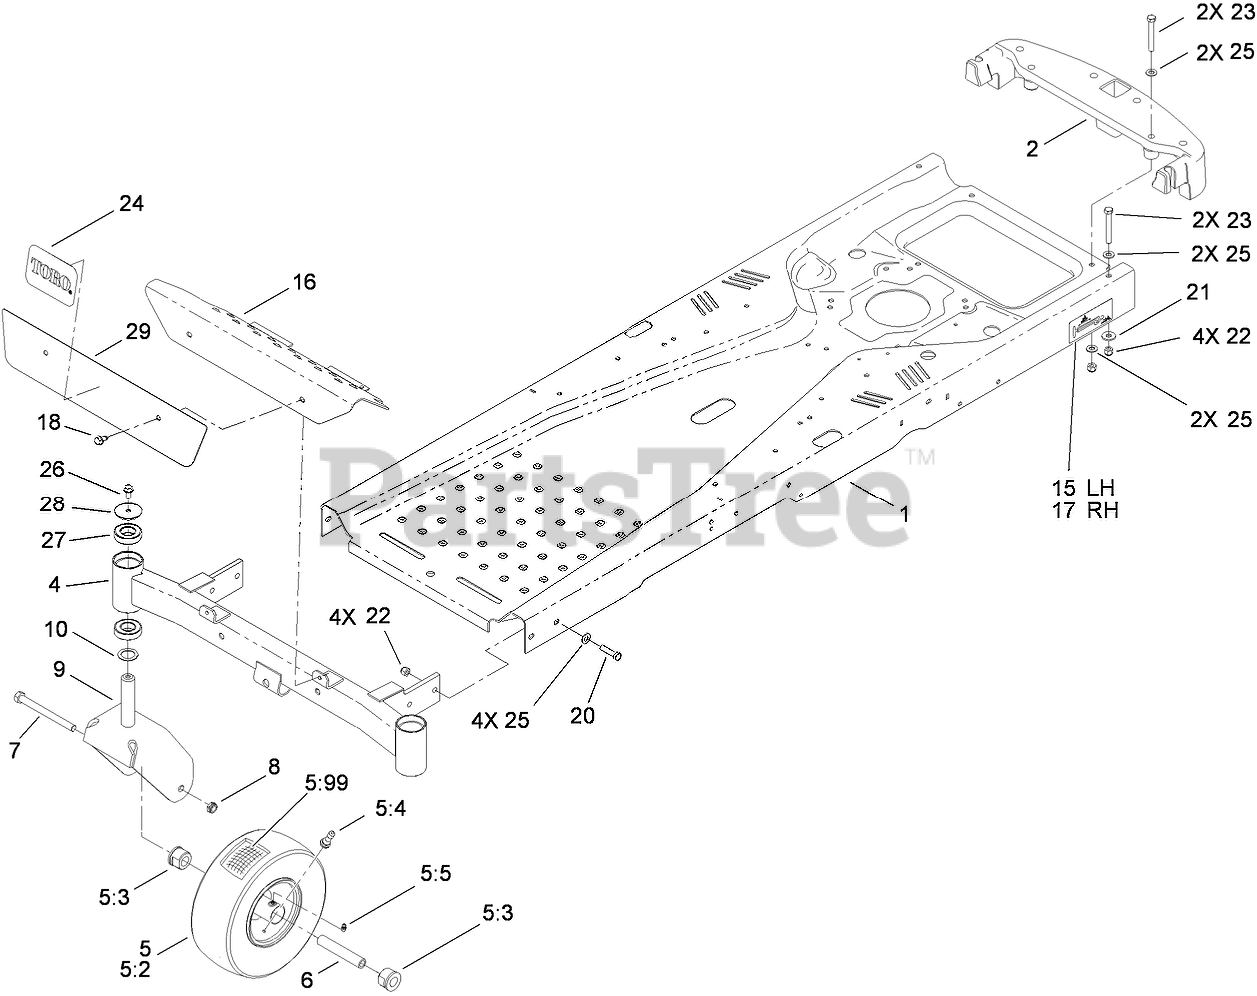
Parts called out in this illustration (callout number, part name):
2	BUMPER-REAR
4	FRONT AXLE ASM
5	11 INCH TIRE AND WHEEL ASM
5:2	TIRE-RIBBED
5:3	BUSHING-FLANGE
5:4	STEM-VALVE
5:5	FITTING-GREASE
5:99	TUBE-INNER
6	BUSHING-SPANNER
7	SCREW-HH
8	NUT-LOCK, NI
9	CASTER FORK ASM
10	WASHER-THRUST
15	DECAL-TRANSPORT, LH
16	FOOTREST
18	SCREW-HWH
20	SCREW-HH
21	WASHER-HARDENED
22	NUT-LOCK, NI
23	SCREW-HH
25	WASHER-FLAT
26	SCREW-HHF
27	BEARING-BALL
28	WASHER
29	PLATE-FOOTREST
